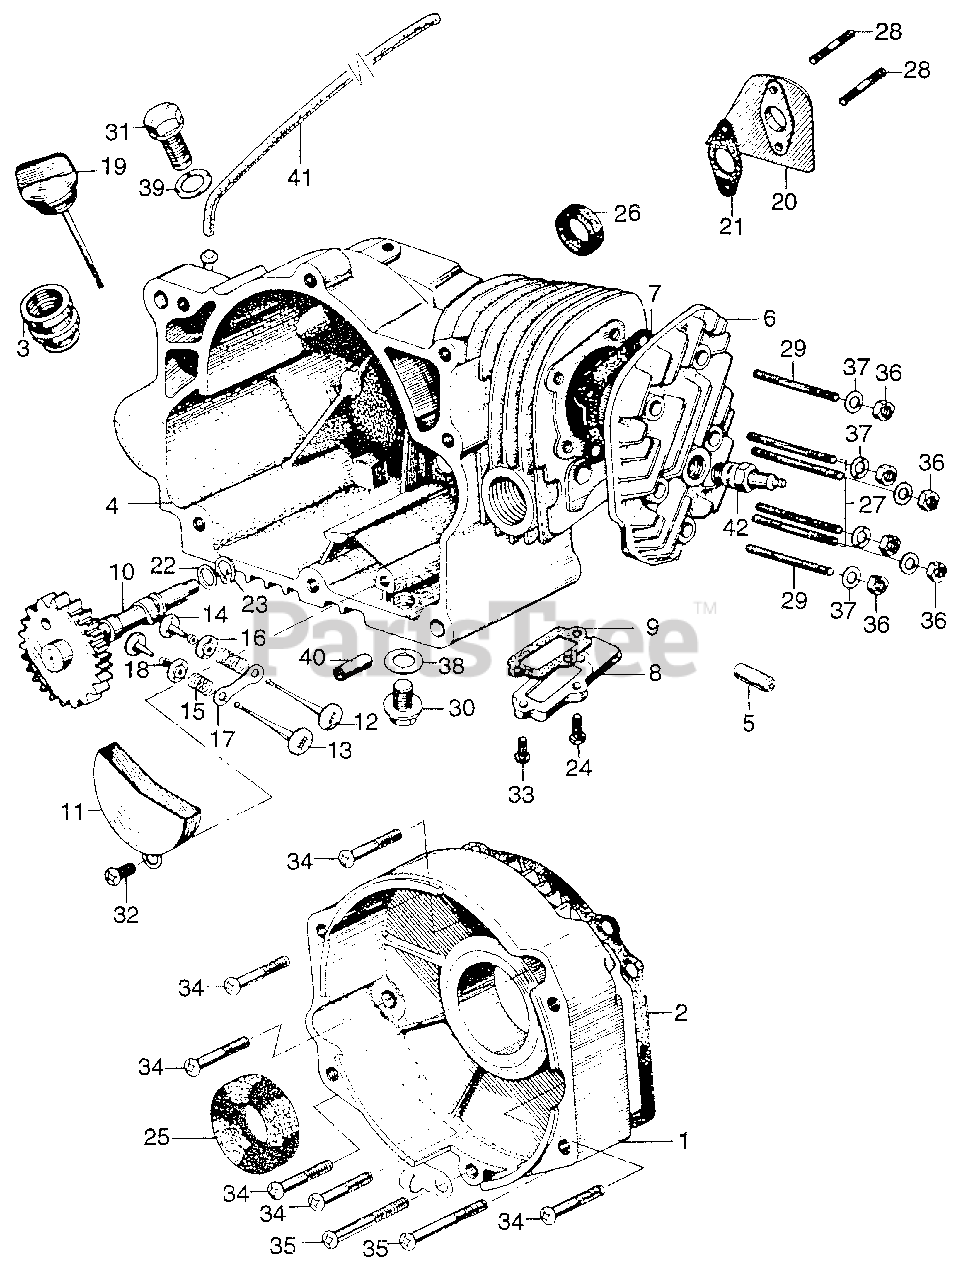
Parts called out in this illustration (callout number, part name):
1	COVER, CRANKCASE
2	GASKET, CRANKCASE COVER
5	GUIDE, VALVE (OS)
6	CYLINDER HEAD
7	GASKET, CYLINDER HEAD
8	COVER, TAPPET
9	GASKET, TAPPET COVER
11	PROTECTOR, GEAR (NOT AVAILABLE)
12	VALVE, IN. (NOT AVAILABLE)
13	VALVE, EX.
14	LIFTER, VALVE (NOT AVAILABLE)
15	SPRING, VALVE (NOT AVAILABLE)
16	RETAINER, VALVE SPRING
17	SEAT, SPRING
18	ADJUSTER, TAPPET CLEARANCE (3. 48-3.51) (NOT AVAILABLE)
18	ADJUSTER C, TAPPET CLEARANCE (3.42-3.45)
18	ADJUSTER F, TAPPET CLEARANCE (3.33-3.36) (NOT AVAILABLE)
18	ADJUSTER, TAPPET CLEARANCE (3.24-3.27) (NOT AVAILABLE)
19	CAP, OIL (NOT AVAILABLE)
19	CAP, OIL
20	INSULATOR, CARBURETOR
21	GASKET, CARBURETOR INSULATOR
22	WASHER (18MM)
23	CIRCLIP (18MM)
24	BOLT, SPECIAL (5MM)
25	OIL SEAL (17X35X6) (NOT AVAILABLE)
26	OIL SEAL (15X24X5)
27	BOLT, STUD (6X45)
28	BOLT, STUD (5X32) (NOT AVAILABLE)
29	BOLT, STUD (6X50)
30	BOLT, DRAIN PLUG (12MM)
31	BOLT, DRAIN PLUG (14MM)
32	SCREW, PAN (5X10)
33	SCREW, PAN (5X18)
34	SCREW, PAN (5X22)
35	SCREW, PAN (5X36)
36	NUT, HEX. (6MM)
37	WASHER, PLAIN (6MM)
38	WASHER, DRAIN PLUG (12MM)
39	WASHER, DRAIN PLUG (14MM)
40	PIN A, DOWEL (8X14)
41	BULK HOSE, FUEL (4.5X3000) (4.5X185)
41	BULK HOSE, FUEL (4.5X3000) (4.5X200)
42	SPARK PLUG (CM6) (NGK)
